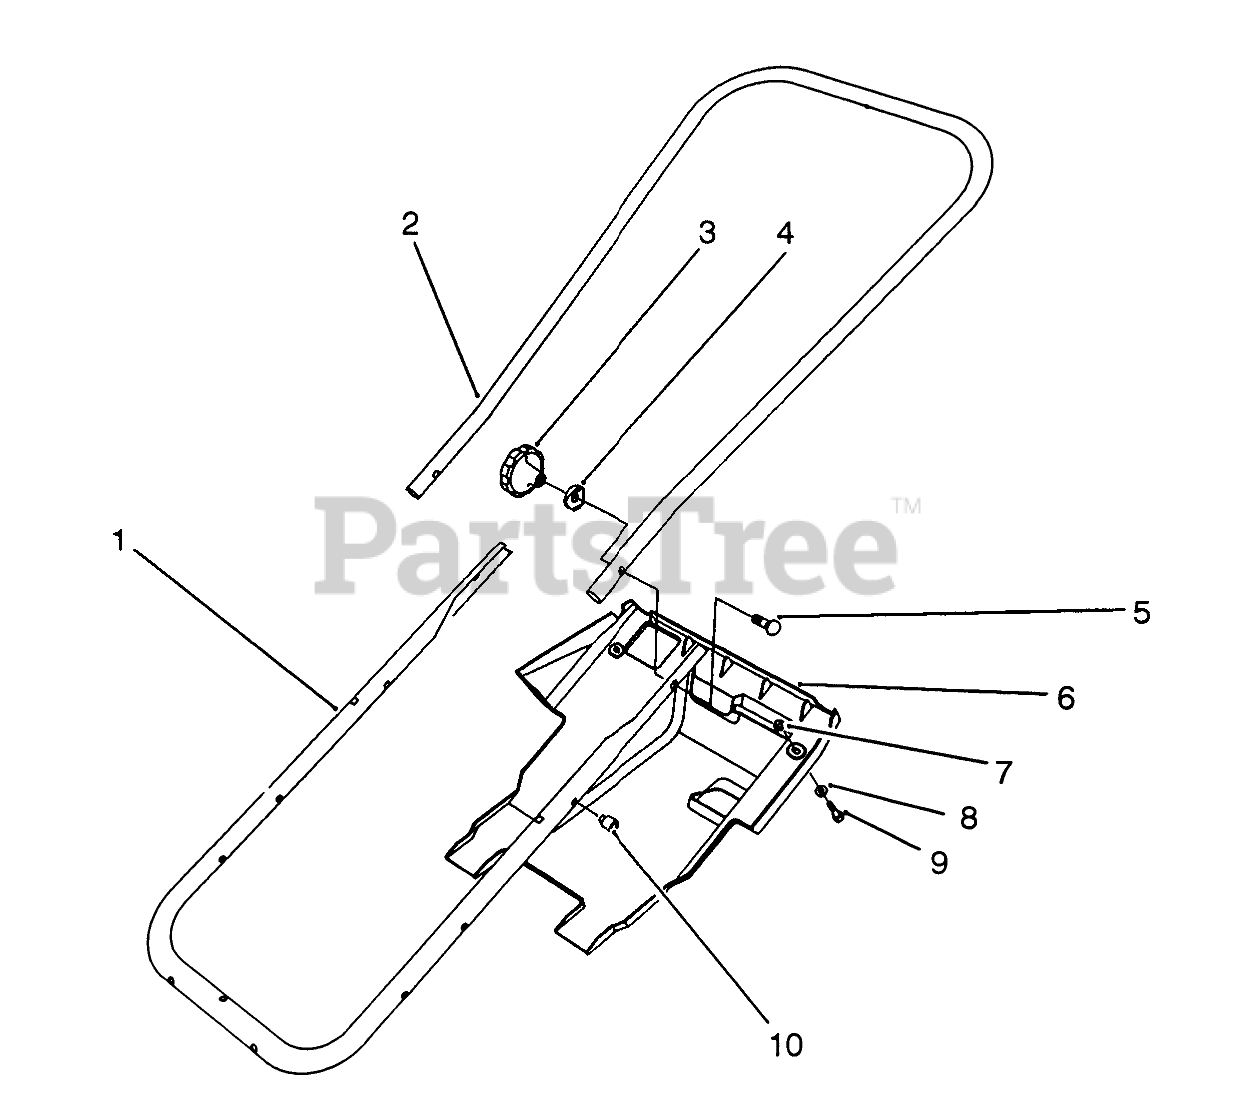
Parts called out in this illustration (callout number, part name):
1	Tube-Frame
2	Handle-Upper
4	WASHER-CURVED
5	SCREW-HANDLE
6	SHROUD
7	Nut-Push
8	WASHER-FLAT
9	SCREW-HWHTF
10	NUT-EXPANSION
